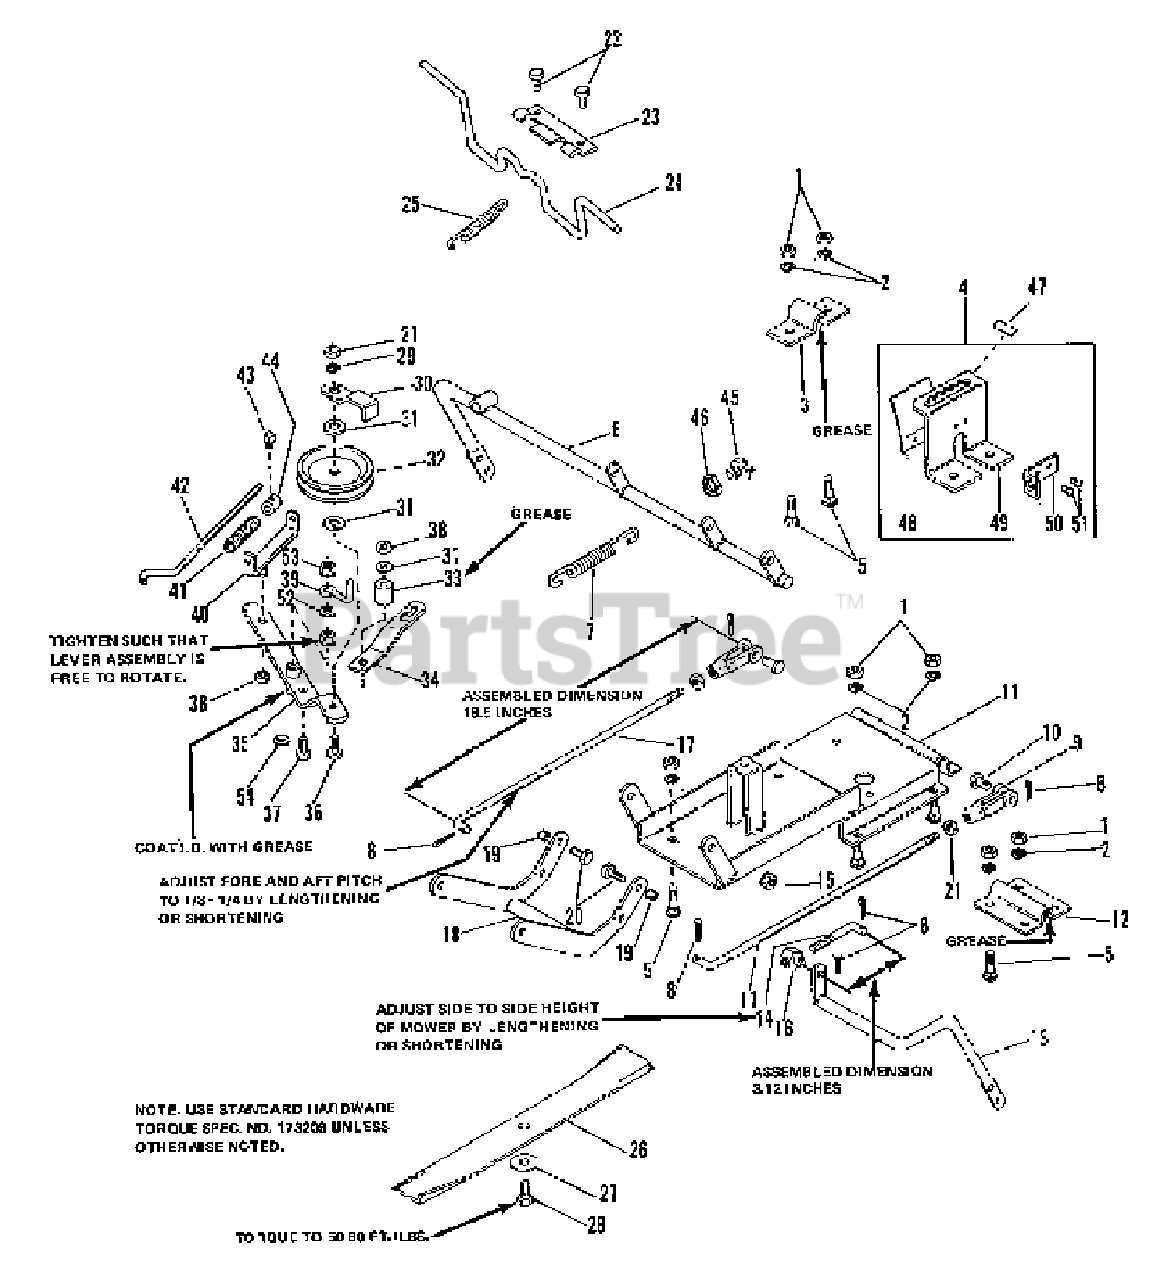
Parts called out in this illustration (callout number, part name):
1	NUT, Hex, 5/16-18
2	LOCKWASHER, 5/16
4	QUADRAND ASSEMBLY
5	BOLT, Carriage, 5/16-18 x 3/4
6	R.H. ROLLER & WHEEL SUPPORT
8	PIN, Cotter, 3/32 x 3/4
9	CLEVIS, Adjusting
10	PIN, Yoke, 3/8
11	SUPPORT ASSEMBLY
12	CLAMP, Wheel Support
13	L.H. ROLLER & WHEEL SUPPORT
15	NUT, Flange, 3/8-16
17	ROD, Height Adjusting
18	ROCKER ARM ASSEMBLY
20	CAPSCREW, 3/8-16 x 1
21	NUT, Hex, 3/8-16
22	SCREW, Taptite, 1/4-20 x 3/8
23	SUPPORT, Brake
26	BLADE
27	WASHER, Spring
28	CAPSCREW, 1/2-20 x 1-1/4
29	LOCKWASHER, 3/8
30	GUIDE, Belt
31	WASHER, Plain, 5/16
32	PULLEY, Idler
34	LEVER, Brake
35	CLUTCH LEVER ASSEMBLY
36	CAPSCREW, 3/8-16 x 1-1/2
37	CAPSCREW, 5/16-18 x 1
38	NUT, Lock, 5/16-18
40	ROD GUIDE ASSEMBLY
42	ROD, Clutch
43	SETSCREW, Square Head, 1/4-20 x 3/8
44	COLLAR, Set
46	NUT, Pal
47	DECAL, Height
50	BRACKET, Switch
52	WASHER, Plain, 3/8
53	NUT, Flange, 7/16-14
